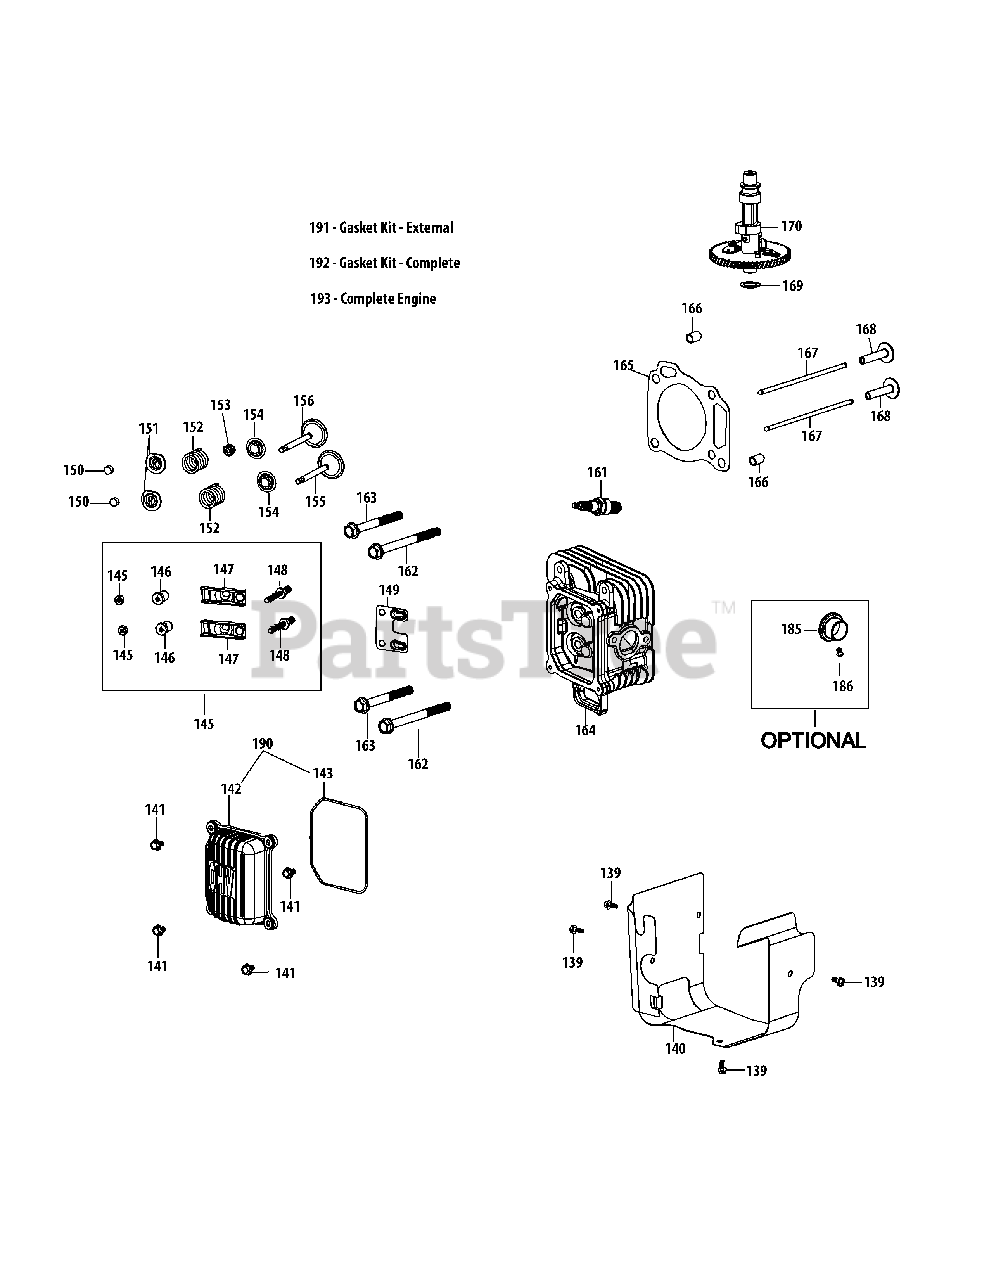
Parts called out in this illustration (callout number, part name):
139	Bolt M5×10
141	Valve Cover Bolt
142	Valve Cover
143	Valve Cover Gasket
144	Rocker Arm Assembly
146	Fulcrum Nut
147	Rocker Arm
148	Rocker Arm Stud
149	Push Rod Guide
150	Exhaust Valve Adjuster
151	Exhaust Valve Spring Retainer
152	Valve Spring
153	Intake Valve Seal
154	Valve Spring Retainer
161	Spark Plug/F6Rtc
162	Bolt M10×1.25×85
163	Bolt /M10×1.25×65
164	Cylinder Head Asm
164	Cylinder Head Kit
165	Cylinder Head Gasket
166	Cylinder Head Dowel 12×16
167	Push Rod Kit
168	Tappet
169	Camshaft Thrust Washer
170	Camshaft Assembly
185	Spark Arrestor
186	Spark Arrestor Screw
190	Valve Cover Kit
191	Gasket Kit - External
192	Gasket Kit - Complete
193	Complete Engine
